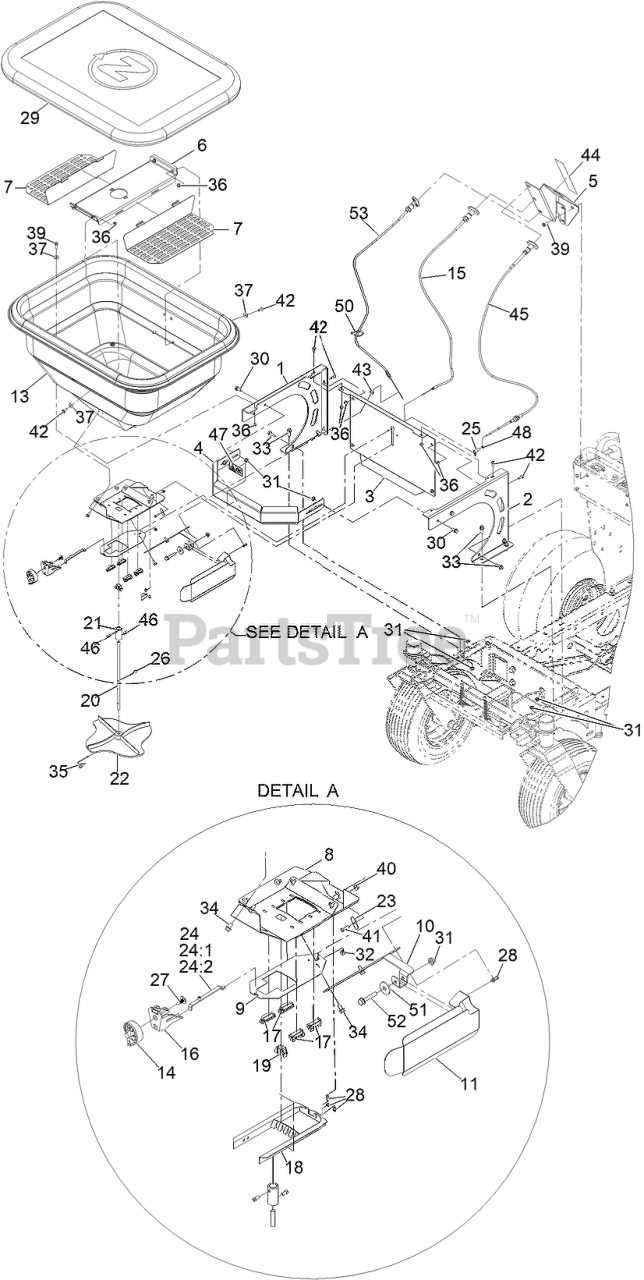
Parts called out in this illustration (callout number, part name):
1	Side-Hopper, Rt
2	Side-Hopper, Lt
3	Backshield-Hopper
4	BUMPER-FRONT, HOPPER
5	Mount-Speedometer
6	PAN-HOPPER, 220
7	SCREEN-HOPPER, 220
8	BASE PLATE, HOPPER, 220
9	Slide-Door, Hopper
10	MOUNT-DEFLECTOR, SIDE
11	Deflector-Side, Spreader
13	ASY-HOPPER 220 LB
15	CABLE-PUSH/PULL
16	MOUNT-DIAL
17	GUIDE-RATE, GATE
18	DIFFUSER
19	HOPPER BOTTOM BEARING
20	SHAFT-HOPPER, 220
21	COUPLER-SS
22	Spinner-Spreader
23	RETAINER, CABLE
24	RATE GATE LINK ASM
24:1	LINK-GATE, RATE
24:2	SCREW-SHOULDER, SLOTTED
25	BALL JOINT-SS
26	WIRE-AGITATOR
27	Footpad Fastener
28	WIRE-STOP
29	COVER-HOPPER, LARGE
30	SCREW-HHF
31	Nut-Hex Flange
32	Nut,NYL Lock,#10-32,ST/ST 18-8
33	SCREW-HHF
34	SCREW-HHF
35	Clip-Spinner
36	Nut-Hex Flange
39	Screw-Hsbhf
40	Nut-Hex Flange
41	SCREW-HH
42	Screw-Hsbhf
43	Grommet-Rubber
44	Decal-Hopper Control
45	CABLE-PUSH/PULL
46	Screw-SQH
47	Decal-Dismemberment Hazard
48	Nut,Hex Jam Mch Scr,10-32,Sst
51	WASHER
52	Screw-HHF
53	Cable-Control, Turn Lock 2.00 Trvl
